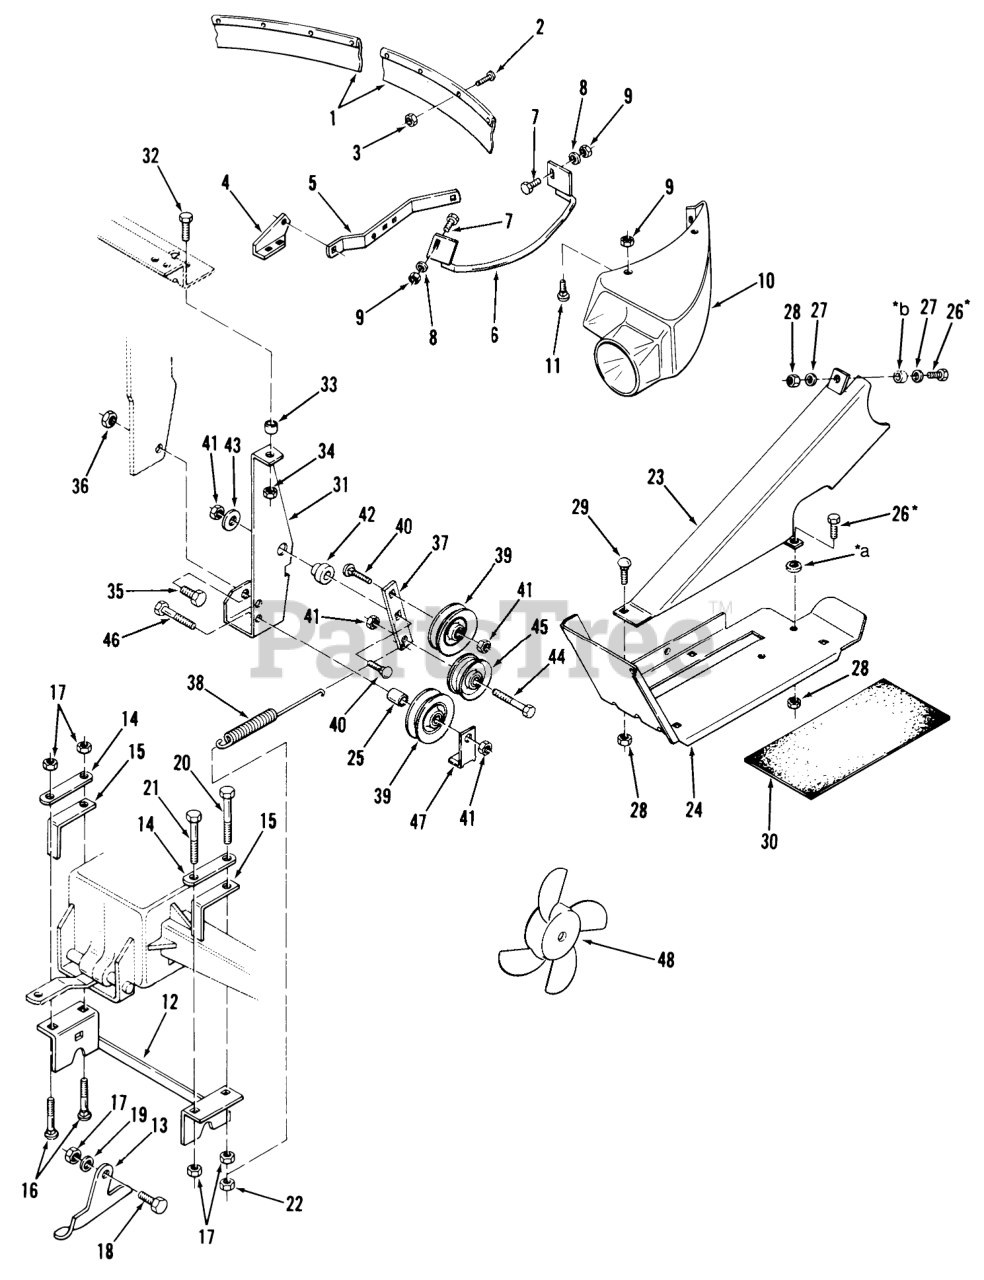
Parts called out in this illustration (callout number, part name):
1	ASSY COVER
2	Screw
3	#10-24 Kep-Nut
4	Deck Bracket-Mower
5	Draft Bar-Mower
6	Blade Guard Assembly
7	Bolt
8	WASHER 5/16 SAE
9	Nut
10	NOZZLE ASSY
11	Bolt Carnage
12	Bracket
13	PLATE-LATCHING
14	BRACKET-REAR LINK MOUNTING
15	SPACER-BRACKET
16	Bolt-Carriage
17	NUT
18	BOLT
19	Washer
20	Bolt 3/8-16 x 4
21	HHCS
22	NUT
23	Belt Guard
24	Footrest
25	SPACER
26	Bolt
27	WASHER 5/16 SAE
28	Nut
29	CARRIAGE BOLT -4
30	PAD-FOOTREST
31	Roller
32	Bolt
33	Spacer
34	Nut
35	Bolt
36	Eslok Nut
37	Idler Arm
38	SPRING-EXTENSION
39	PULLEY-IDLER STATION
40	Carriage Bolt 3/8-16 x 1 1/2 Short Neck
41	Nut
42	SPACER-CLUTCH LINK
43	WASHER
44	Bolt
45	IDLER PULLEY
46	Bolt
47	BRACKET GUARD
